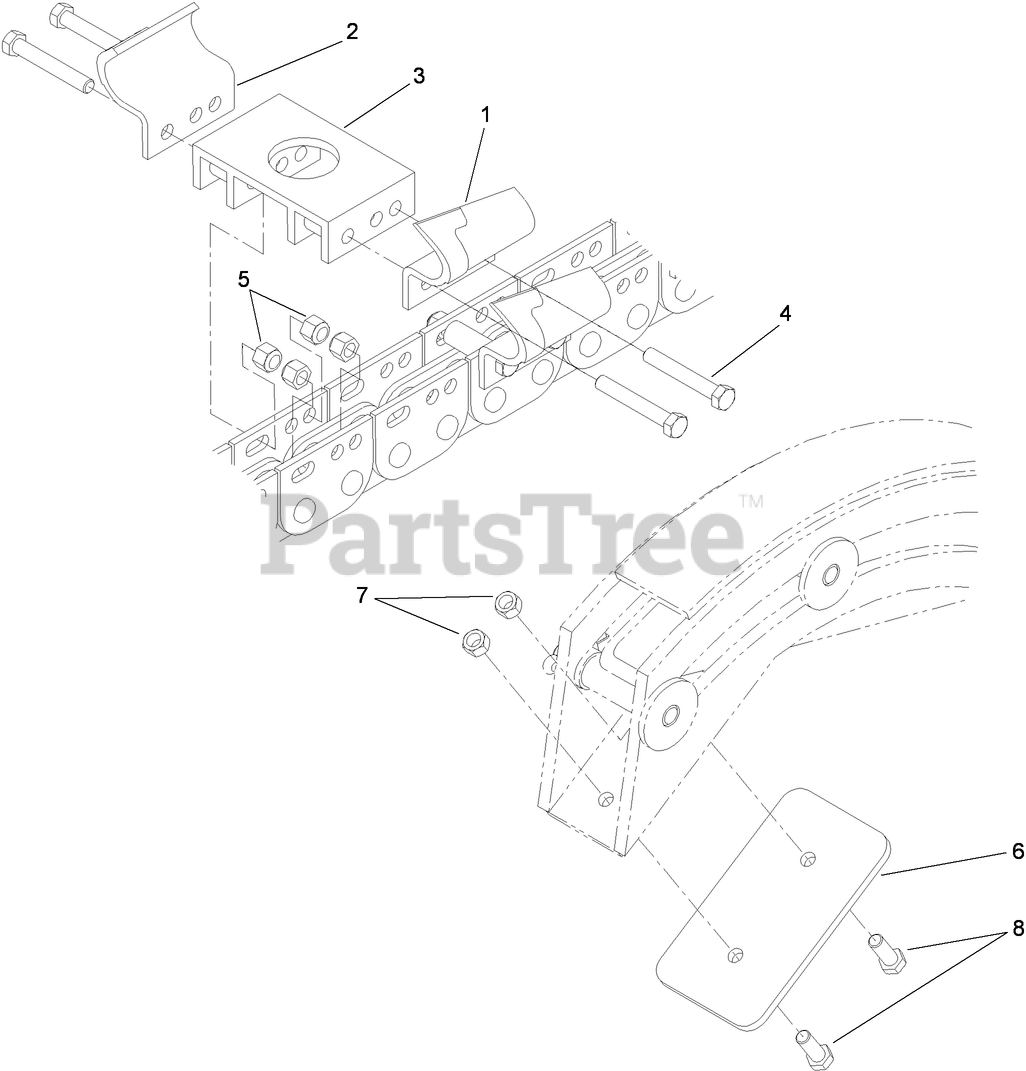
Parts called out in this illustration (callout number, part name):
1	TOOTH-SOIL, LH
2	TOOTH-SOIL, RH
3	ADAPTER-8 INCH
4	SCREW-HH
5	NUT-LOCK
6	PLATE-DEFLECTOR, 8 INCH
7	NUT-LOCK, SIDE
8	SCREW-HH
